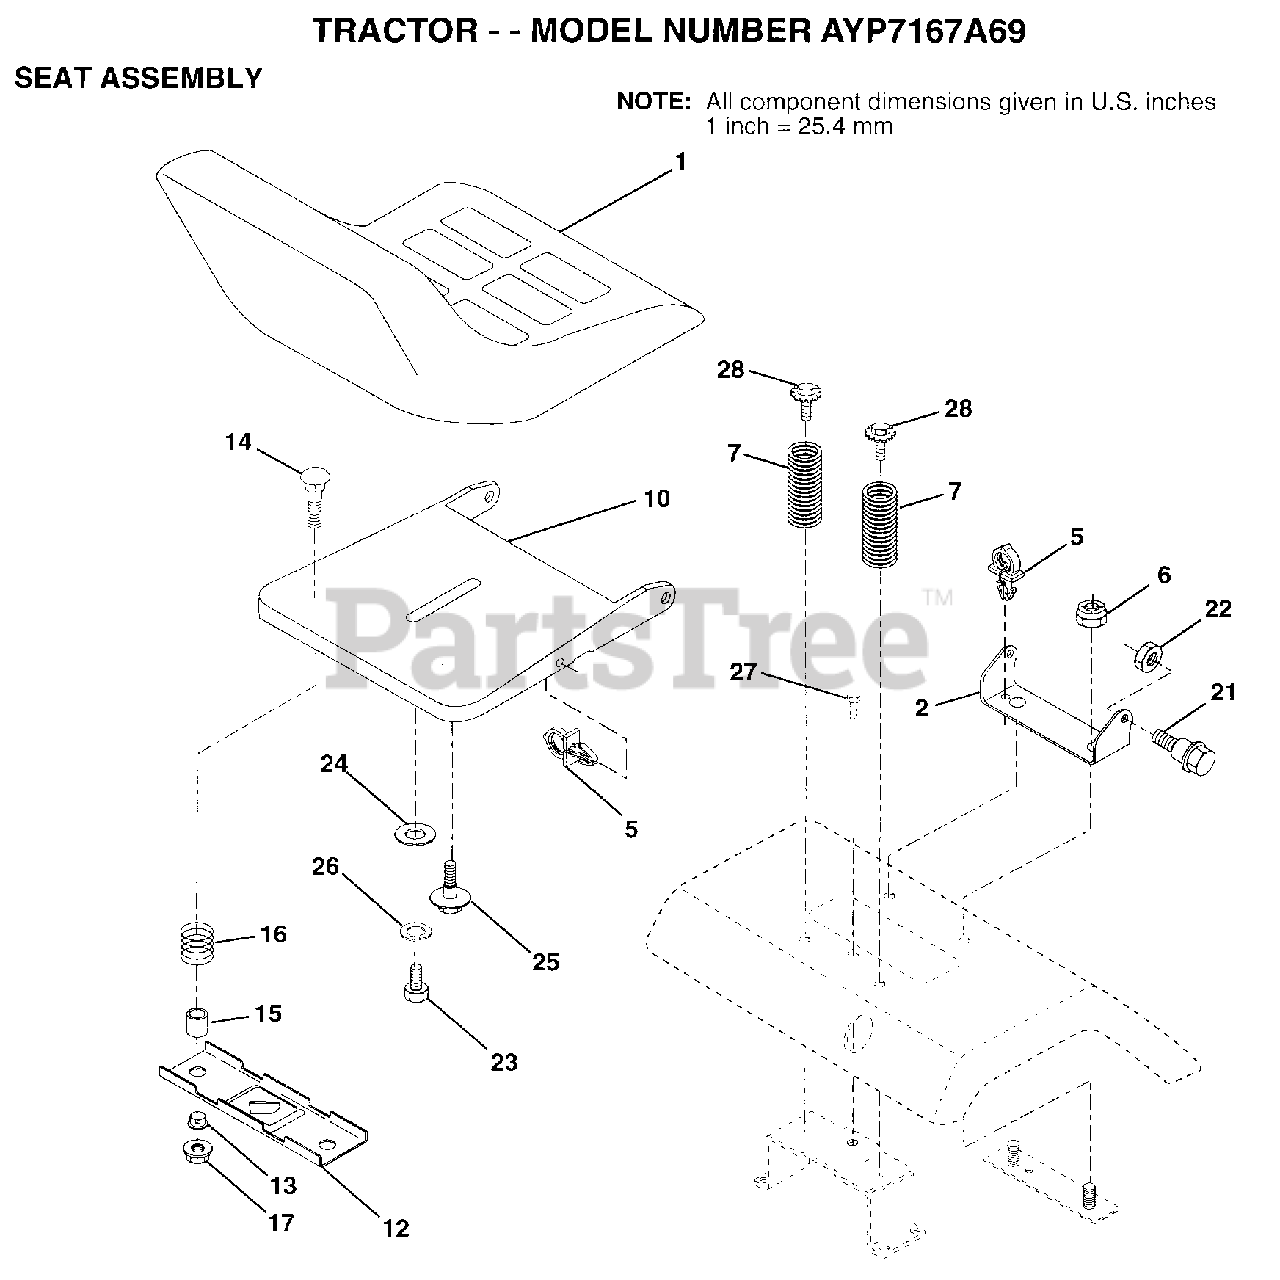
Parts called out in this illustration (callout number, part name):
1	SEAT
2	BRACKET PVT SEAT
5	CLIP.PUSH-IN.HING
6	NUT
7	SPRING COMPRESSIO
8	SCREW LT
9	WASHER
12	BRKT SWITCH
13	BUSHING
15	SPLIT SPACER
16	SPRING
21	BOLT.SHLD.5/16-18
22	NUT
23	BOLT
24	WASHER
25	"BOLT,SHOULDER"
26	LOCKWASHER
27	SCREW LT
